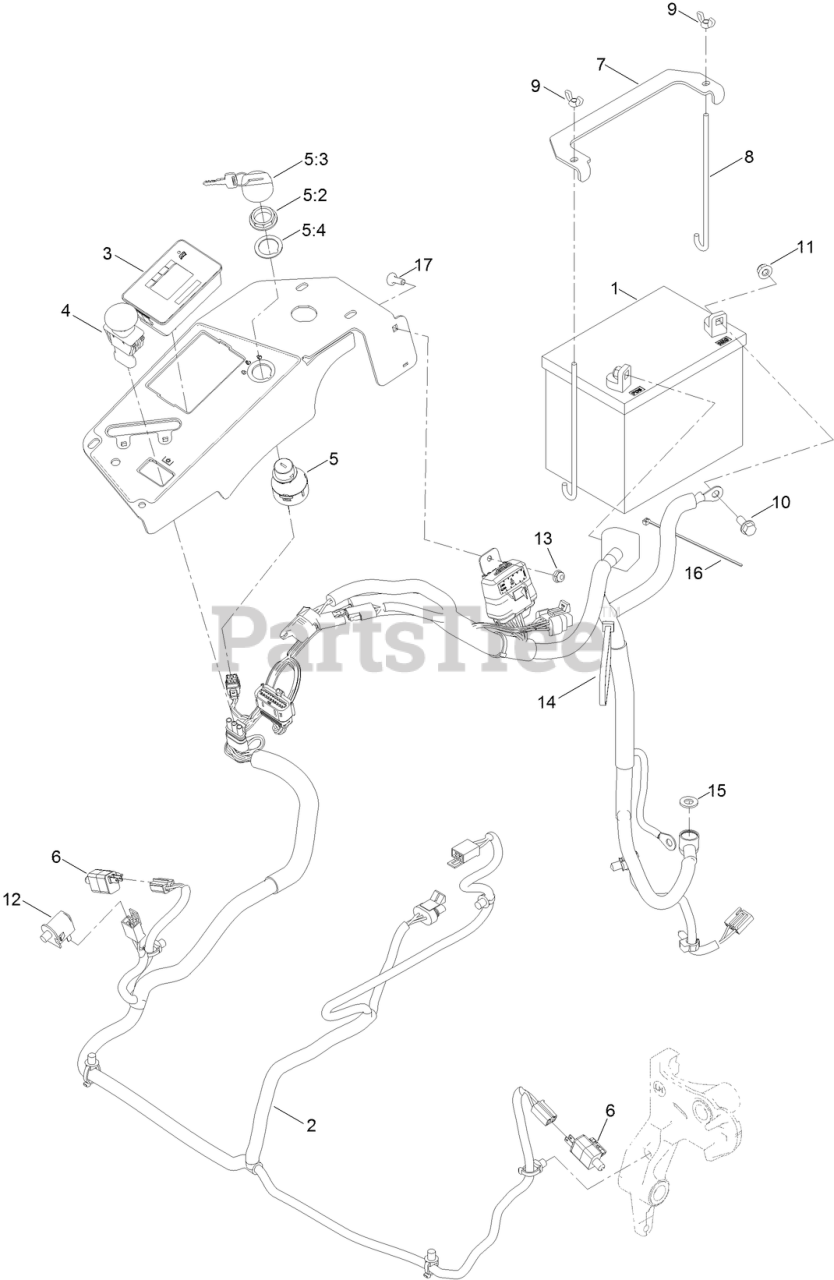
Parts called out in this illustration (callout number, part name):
1	BATTERY-DRY
2	WIRE HARNESS ASM
3	METER-HOUR
4	SWITCH-PTO, SEALED
5	IGNITION SWITCH ASM
5:2	NUT-MOUNTING
5:3	IGNITION KEY SET
5:4	WASHER-BACKUP
6	SWITCH
7	STRAP-TIE DOWN, BATTERY
8	BOLT-HOLDDOWN
9	WINGNUT
10	SCREW-HHF
11	NUT-HF, NI
12	SWITCH-BAIL
13	NUT-HF
14	TIE-CABLE
15	WASHER-FLAT
16	TIE-CABLE
17	BOLT-CARR
